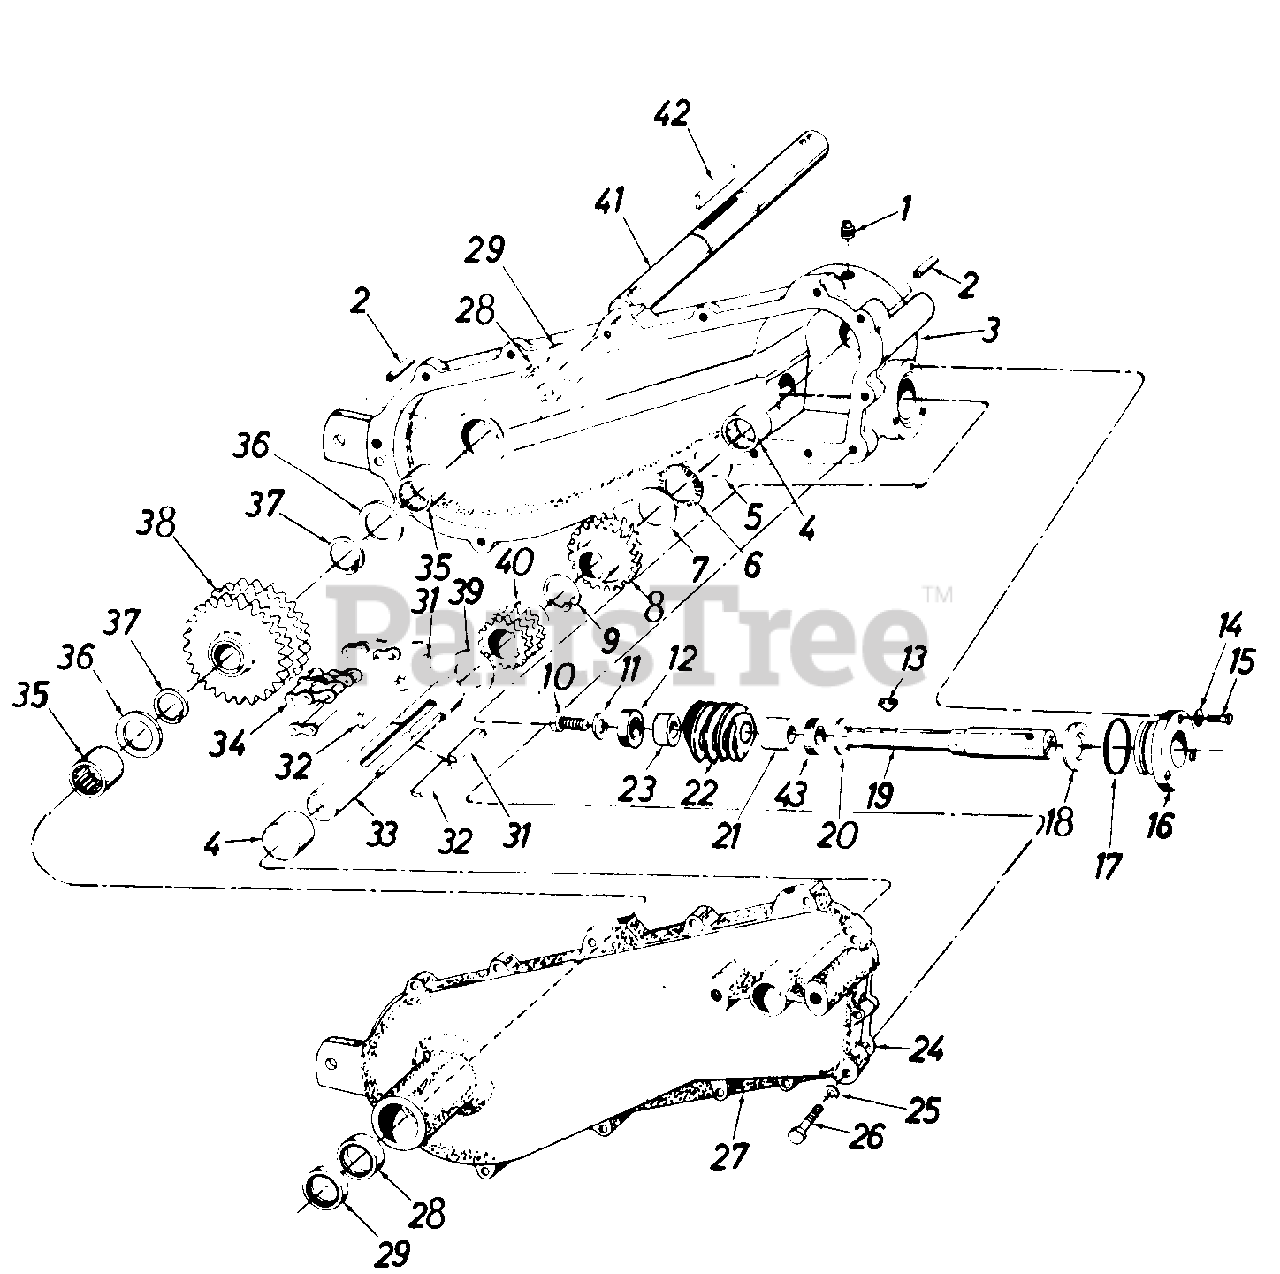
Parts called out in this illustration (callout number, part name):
1	Sq. Hd. Pipe Plug with Vent
2	Spring Pin Spiral 5/16" Dia. x 1.75" Lg.
3	Gear Case-L.H. Half
4	Needle Bearing
5	Thrust Race 1.25" I.D. x .126 Thk.
6	Thrust Bearing 1.25" I.D. x 1.977 O.D.
7	Thrust Race 1.25" I.D. x .303Thk.
8	Worm Wheel
9	Snap Ring-for 1.25" Dia. Shaft
10	Hex Lock Scr. 5/16-24 x .75" Lg.
11	Belleville Wash. 5/16" Dia.
12	Ball Bearing.669 I.D. x 1.850.D. x.55
13	#9 Hi-Pro-Key 3/16" x 3/4" Dia.
14	L.-Wash. 1/4" Scr.*
15	Hex Scr. 1/4-20 x .88" Lg.*
16	End Cap
17	"O"-Ring
18	Oil Seal .875" I.D. x 1.503 O.D.
19	Worm Input Shaft
20	F I .-Wash. .793 I.D. x 1.240 O.D.
21	Clutch Idler Bushinq
22	Worm Gear
23	Spacer
24	Gasket
25	L.-Wash. 5/16" Scr.*
26	Hex Scr. 5/16-18 x 1.75" Lg.*
27	Gear Case-R.H. Half
28	Oil Seal 1.25" I.D. x 2.004"O.D.
29	Oil Seal 1.25" I.D. x 2.004"O.D.
31	Sq. Key 5/16 x 1.25" Lg.*
32	Sq. Key 5/16 x 1.75" Lg.*
33	Worm Gear Shaft
34	Chain w/master link #60 x 39
35	Needle Brg. 1.25" I.D. x 1.927"O.D.
36	Thrust Bearing
37	Tru arc Snap Ring
38	Sprocket-25 Teeth
39	Thrust Bearing
40	Sprocket 13 Tooth
41	Tine Shaft
42	Sq. Key 5/16" x 2.0" Lg.*
43	Ball Bearing.787 I.D. x 2.0480.D.
